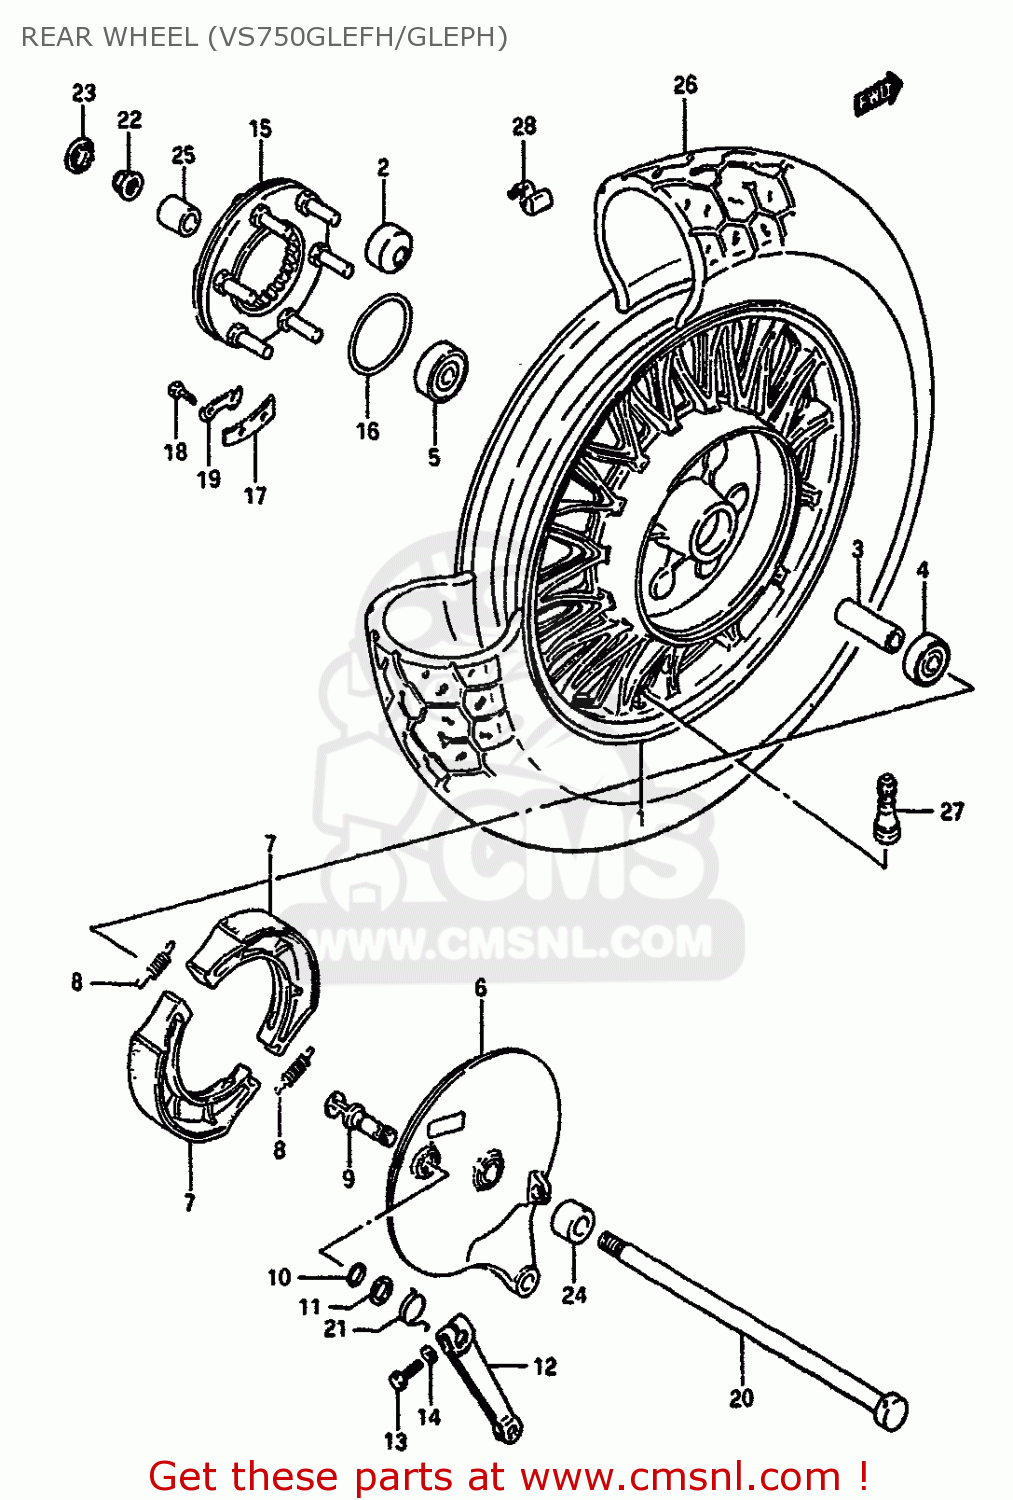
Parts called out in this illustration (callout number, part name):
1	WHEEL SET,REAR (3.00-15)
2	BUSH
3	SPACER,REAR HUB BEARING
4	BEARING
5	BEARING
6	PANEL,REAR BRAKE ANCHOR
7	SHOE SET,BRAKE (MCA)
8	SPRING,BRAKE SHOE
9	CAM,RR BRAKE
10	O-RING,BOSS
11	WASHER (15X24X1.6)
12	LEVER,RR BRAKE CAM
13	BOLT
14	WASHER,LOCK
15	JOINT ASSEMBLY,REAR HUB DRUM
16	O RING(D:2.1,ID:65)
17	WASHER,THRUST(T:1.6)
18	BOLT(6X16)
19	WASHER
20	AXLE,REAR
21	SPRING
22	NUT
23	CAP,RR AXLE,R
24	SPACER,REAR AXLE,RIGHT
25	SPACER,REAR AXLE,LEFT
26	TIRE
27	VALVE ASSEMBLY,WHEEL RIM,P
28	BALANCER,WHEEL
